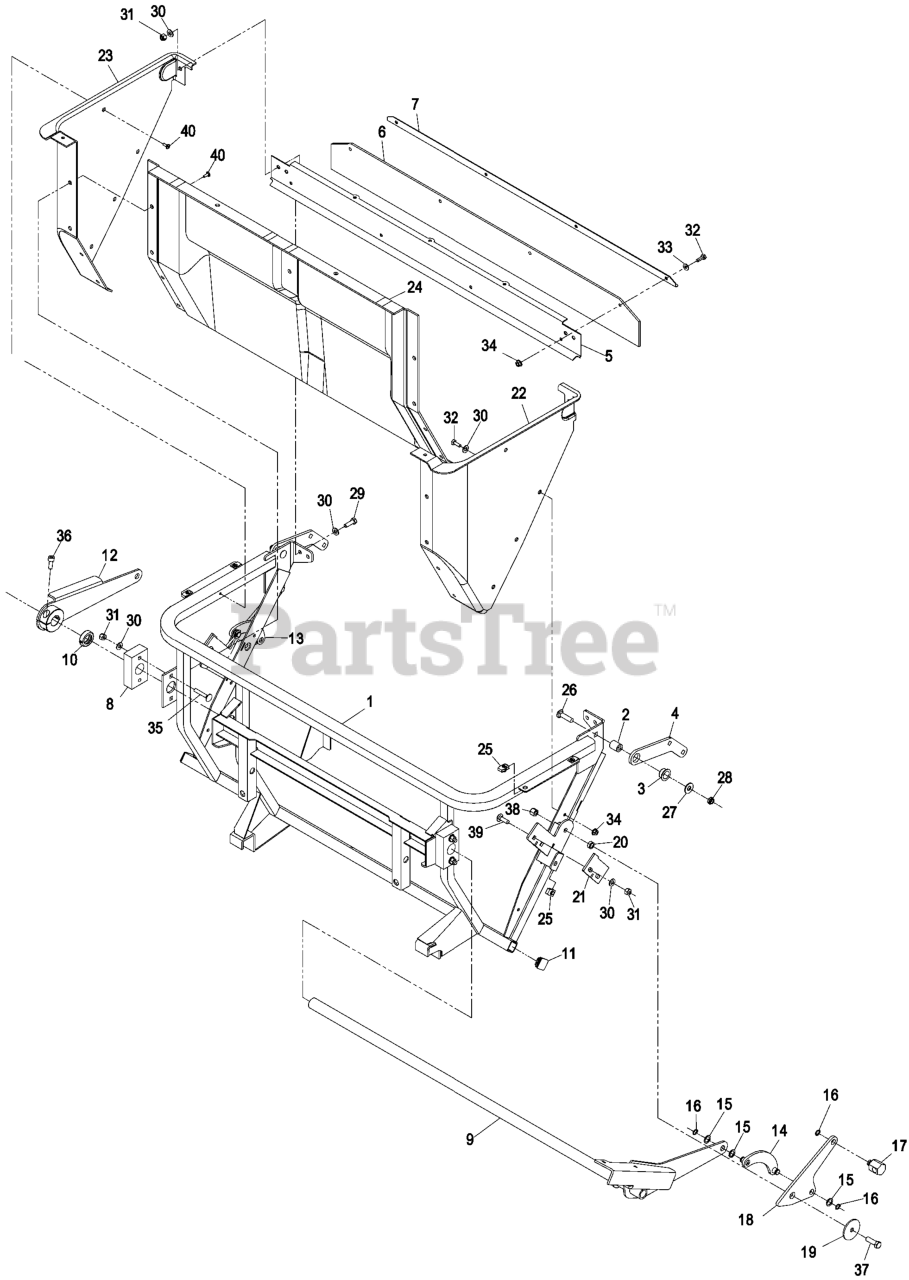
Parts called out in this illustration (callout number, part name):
2	PIN-PIVOT, HINGE
3	BEARING
4	PLATE-HINGE
5	PLATE-REAR
6	SEAL-DOOR
7	STRAP-HOLD DOWN
8	BEARING
9	BELLCRANK
10	SHAFT-COLLAR
13	LINK-RH
14	LINK-LH
15	WASHER-NYLON
16	RING-RETAINING
17	TRUNNION-LINK
18	ARM-LINKAGE, DOOR
20	BEARING-LINKAGE, PIVOT
21	STOP-LINKAGE
22	PANEL-BAGGER, LH
23	PANEL-BAGGER, RH
24	PANEL-BAGGER
25	Nut, Retainer 1/4-20
26	SCREW-CARR
27	WASHER-FLAT
29	SCREW-HH
30	WASHER-PLAIN
31	NUT-LOCK, NI
32	SCREW-HH
33	WASHER-FLAT
35	BOLT-CAR
36	SCREW-HSH
37	SCREW-HH
38	NUT-LOCK, NI
39	BOLT-CARR
40	RIVET-BLIND
